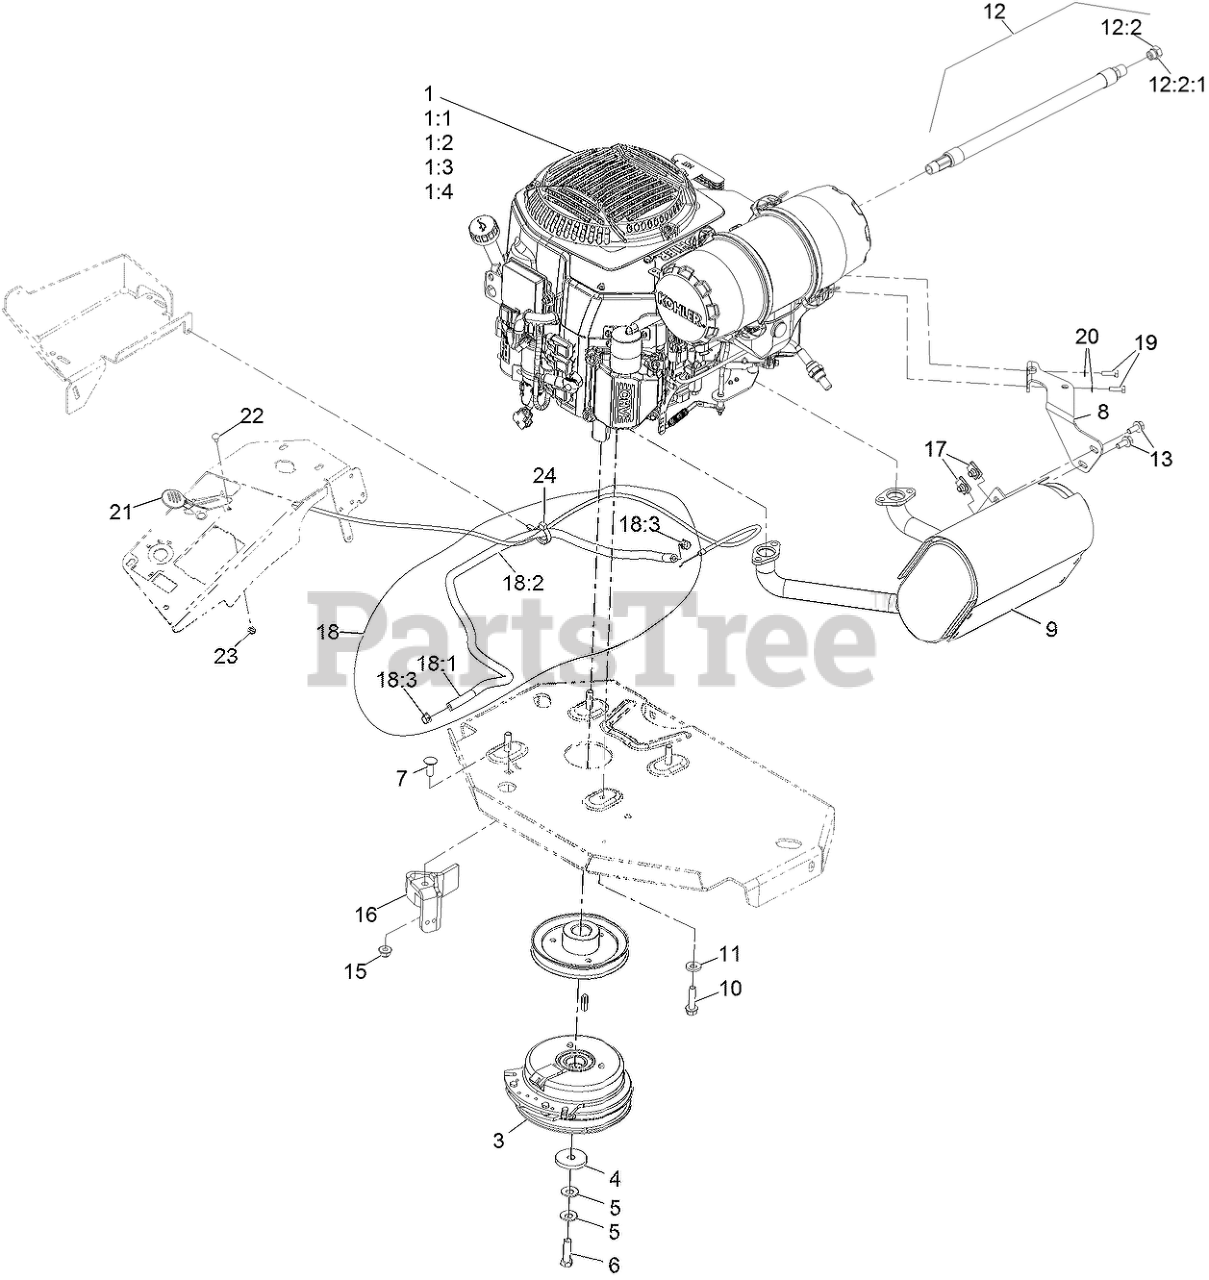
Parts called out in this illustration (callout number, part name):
1:1	Kohler 52 050 02-S Engine Oil Filter
1:2	Kohler 25 083 01-S Engine Air Filter
1:3	Kohler 25 083 04-S Safety Filter
1:4	Kohler 25 050 42-S Fuel Filter
3	CLUTCH KIT
4	WASHER-CLUTCH
5	WASHER-SPRING
6	SCREW-HH 7/16-20 X 1 1/2 W/LOCTITE
7	SCREW-CARR
8	MUFFLER BRACKET KIT
9	MUFFLER KIT
10	SCREW-HWH
11	WASHER-BELLEVILLE
12	OIL DRAIN HOSE ASM
12:2	PLUG-HH
12:2:1	O-RING
13	SCREW-HHF
15	NUT-HF, NI
16	CLUTCH-ANCHOR
18	FUEL LINE ASM
18:1	HOSE-FUEL
18:2	SLEEVE-THERMAL
18:3	CLAMP-HOSE
19	SCREW-HH M6-1 X 20Mm W/Patch
20	WASHER-SPRING
21	ASM,THROTTLE CABLE
22	BOLT-CARR
23	NUT-LOCK, NI
24	CLAMP-HOSE
